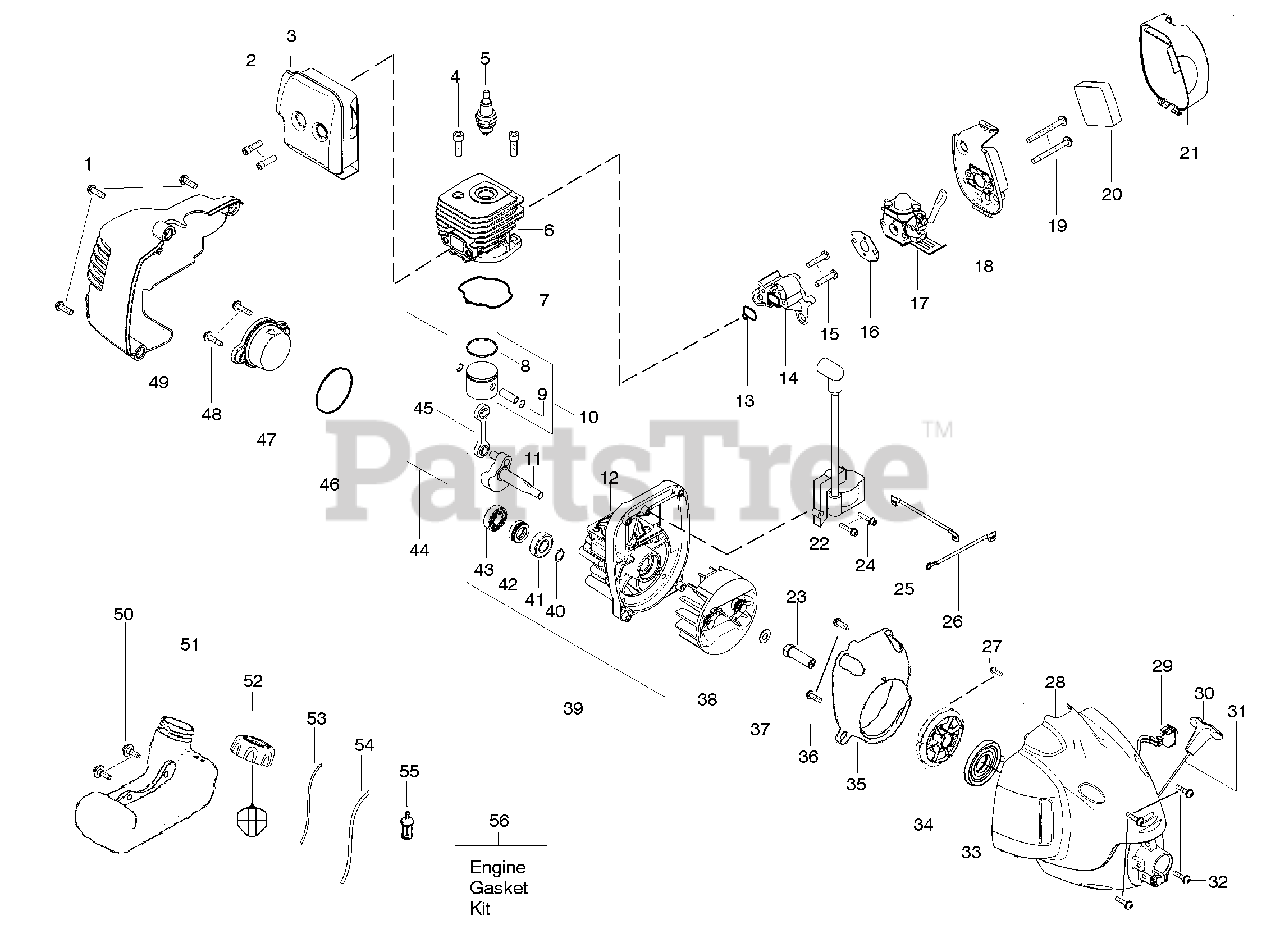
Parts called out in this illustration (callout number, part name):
3	Assy-Muffler/Shield
4	Screw-Cylinder
5	Spark Plug (RCJ 6Y)
7	Seal-Cylinder (kit)
8	Piston Ring
9	Retainer-Piston Pin
10	Kit - Piston
11	Assy-Crankshaft
12	Assy-Crankcase
13	Seal-Cyl/Carb.(kit)
14	Adapter-Carb.
16	Gasket-Carb. (kit)
17	Kit-Carb. Zama (C1U-W18)
17	Kit-Carb. Walbro ( WT-669)
20	Foam-Air Filter
21	Cover-Air Box
22	Ignition Module
23	Coupling-Drive
25	Assy-Leadwire
26	Assy-Ground Wire
28	Assy.-Fan Hsg
30	Handle-Starter
32	Screw
33	Spring-Starter
34	Kit-Starter Pulley
35	Baffle
38	Assy-Flywheel
39	Assy-C'case & C'shaft
40	Retain. Ring-C'shaft
41	Outer Bearing
43	Inner Bearing
44	Kit-Piston/Rod
45	Assy-Connecting Rod
46	O-Ring-C'case (kit)
47	Assy-Plug
50	Retainer-Tank
51	Assy-Fuel Tank
52	Assy-Fuel Cap
53	Kit-Fuel Line (Small)
54	Kit-Fuel Line (Large)
55	Assy-Fuel Pickup
56	Kit-Engine Gasket
